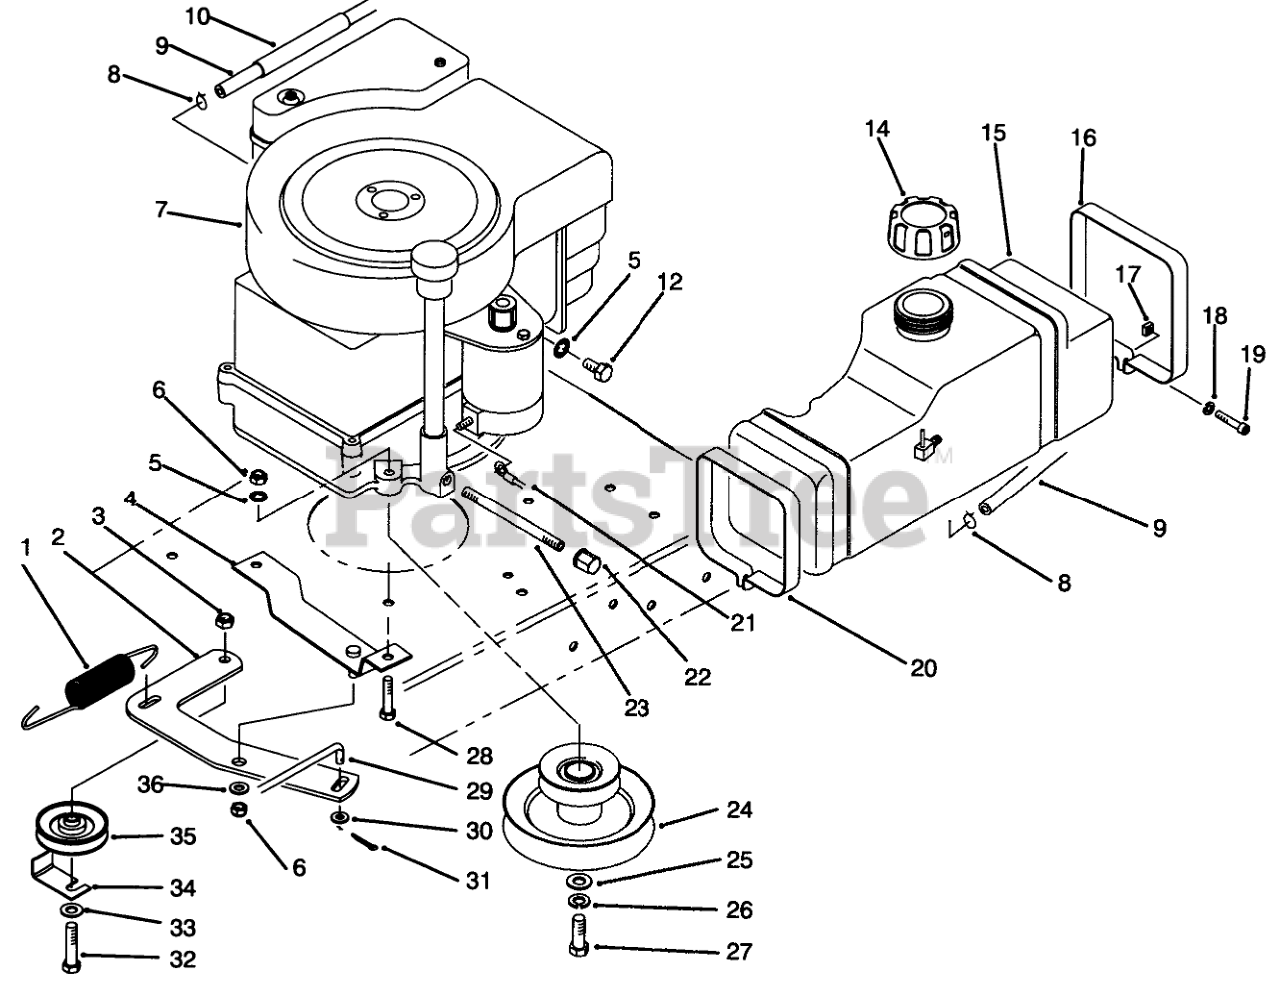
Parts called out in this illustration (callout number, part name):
1	SPRING-TRACTION
2	Plate-Mounting, Idler
3	NUT-LOCK, NI
4	Bracket W.A.-Traction
5	WASHER-LOCK, INTERNAL
6	NUT-LOCK, NI
8	CLAMP-HOSE
9	HOSE - FUEL
10	SUPPORT-FUEL LINE
12	SCREW-HWHTF
14	GAS CAP ASM
15	TANK-5 QT GAS
16	Retainer-Front
17	NUT-SQUARE
18	WASHER-LOCK
19	SCREW-HSH
20	Retainer-Rear
21	WIRE ASM
22	CAP-PIPE
23	NIPPLE
24	PULLEY-ENGINE
25	WASHER-FLAT
26	WASHER-LOCK
27	SCREW-HH
28	SCREW-HH
29	ROD-TRACTION
30	WASHER-FLAT
31	PIN-COTTER
32	SCREW-HH
33	WASHER-FLAT
34	RETAINER-BELT
35	PULLEY-IDLER
36	WASHER-FLAT
